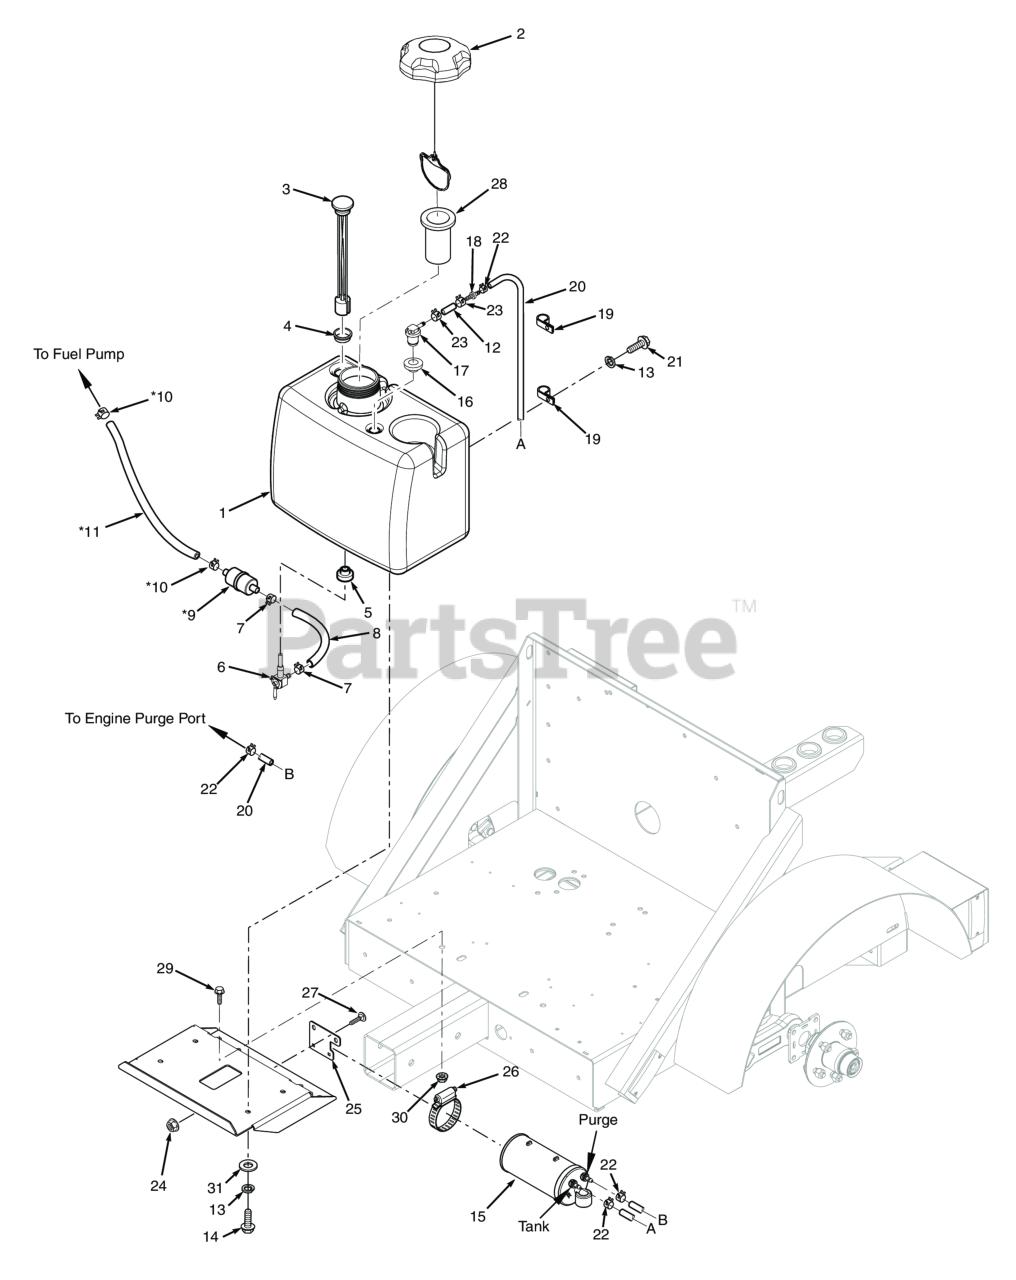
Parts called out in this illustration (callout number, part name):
1	Fuel Tank, TL20W
2	Fuel Cap w/ Tether (E.P.A.)
3	Fuel Gauge Assembly
4	Grommet, Fuel Gauge
5	Bushing, 0.56" Dia. Viton
6	Valve, Fuel Shut Off w/Screen
7	Clamp, Fuel Hose 1/4" Hose I.D.
8	Fuel Hose, 1/4" I.D. Non-Perm (791DFI Fuel Return) - Order by Inch
9	Fuel Filter (contact engine manufacturer)
10	Clamp (contact engine manufacturer)
11	Fuel Hose (contact engine manufacturer)
12	Hose, 1/4" Vapor Recovery (order by inch)
13	Lockwasher, 5/16 (.317 x .586 x .078) Helical Spring
14	BOLT, SERRATED FLANGE HEX HEAD 5/16-18 X 3/4"
15	Carbon Canister - SVR-36A / SVR-48V
16	Grommet, Viton,
17	Remote Vent, No Valve
18	Mender, 1/4 x 3/16 w/0.02 Hole
19	Clamp, Cable - .375 Dia.
20	Hose, Vapor Recovery 3/16" (order by inch)
21	BOLT, SERRATED FLANGE HEX HEAD 5/16-18 X 3/4"
22	Clamp, Vapor Recovery Hose 3/16"
23	CLAMP, FUEL HOSE(KAWASAKI ONLY)
24	Nut, Serrated Flange 5/16-18 (Right Front Engine Mounting, Briggs and Kohler Only)
25	Bracket, Cannister Mount
26	Clamp, 3-1/2" Max. Dia.
27	Bolt, Carriage 5/16-18x1" (large frame units only)
28	Tube, Fuel Tank Insert - 4"
29	Bolt, Hex Head 1/2-13 x 1-1/4"
30	Nut, Hex Serrated Flange 1/2-13
31	Flatwasher, 5/16-.375 x .875 x .083 (35BV & 37BV-EFI)
